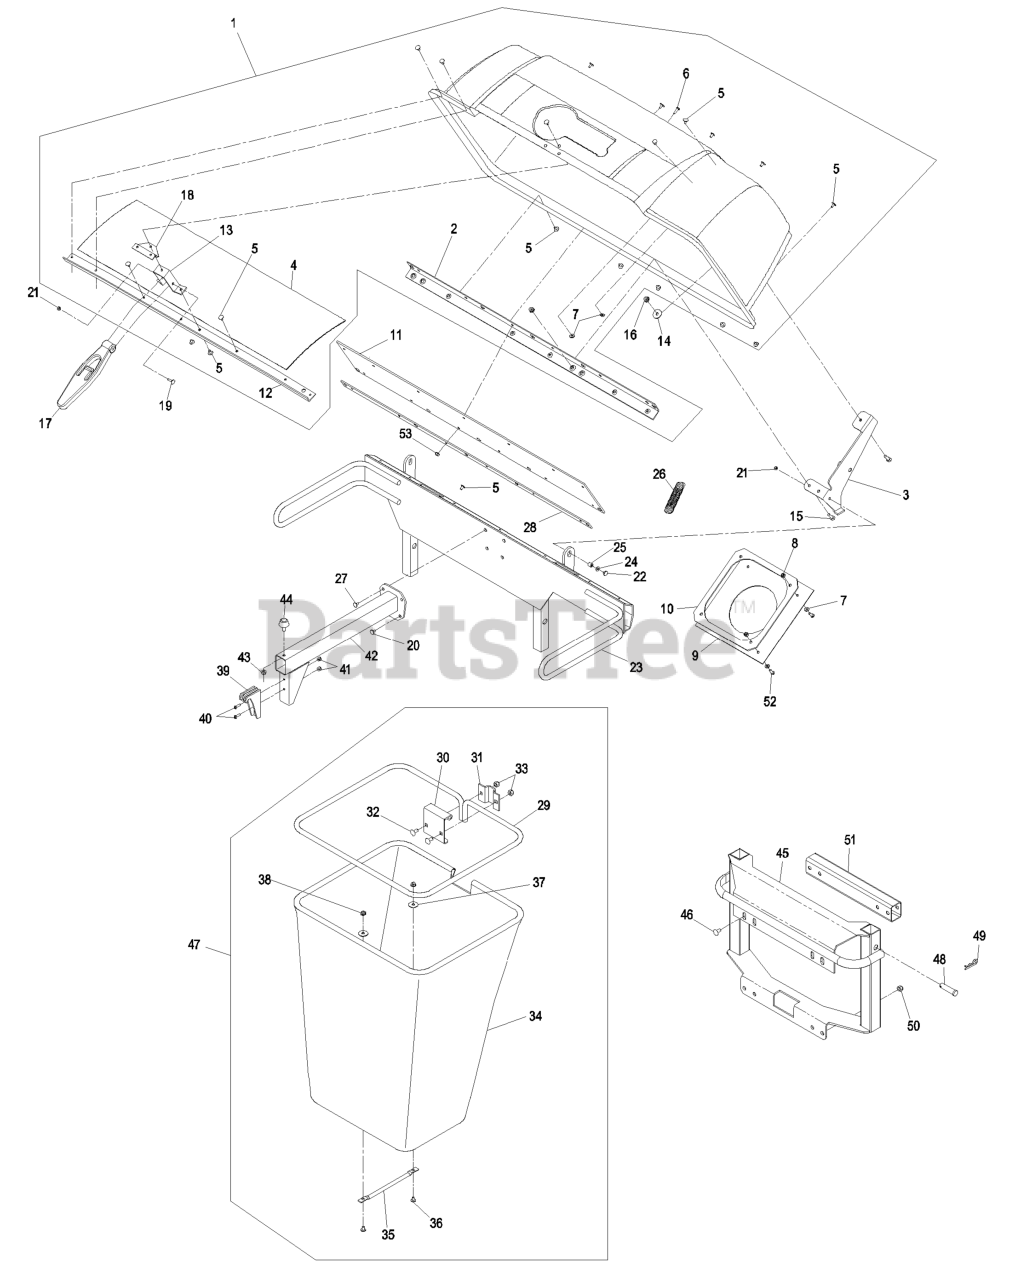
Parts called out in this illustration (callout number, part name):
1	ASM, HOOD
2	STIFFENER-BAGGER, TOP
3	HINGE ASM
4	SCREEN-BAGGER
5	RIVET-BLIND
6	SCREW-HEAD, TRUSS
7	WASHER-FLAT
8	NUT-LOCK, NI
9	SEAL-CHUTE
10	CLAMP-SEAL
12	SUPPORT-SCREEN
13	ANCHOR-LATCH
15	SCREW-HH
18	REINFORCEMENT-LATCH
19	SCREW-HH
20	SCREW-HH
21	NUT-LOCK, NI
22	SCREW-HH
23	BAGGER UPRIGHT ASM
24	WASHER-FLAT
26	SPRING-EXTENSION
27	SCREW-HSBH
28	PLATE-BACKING
29	FRAME-BAG
30	HANGER-BAG
32	BOLT-CARR
33	NUT-LOCK, NI
35	HANDLE-BAG
36	BOLT-CARR
38	NUT-LOCK, NI
40	SCREW-PPH
42	SUPPORT-BAG
45	BAGGER MOUNT ASM
46	SCREW-HH
48	PIN-CLEVIS
49	PIN-COTTER
51	TUBE,SPACER
52	SCREW-PPH
53	NUT-LOCK, SIDE
